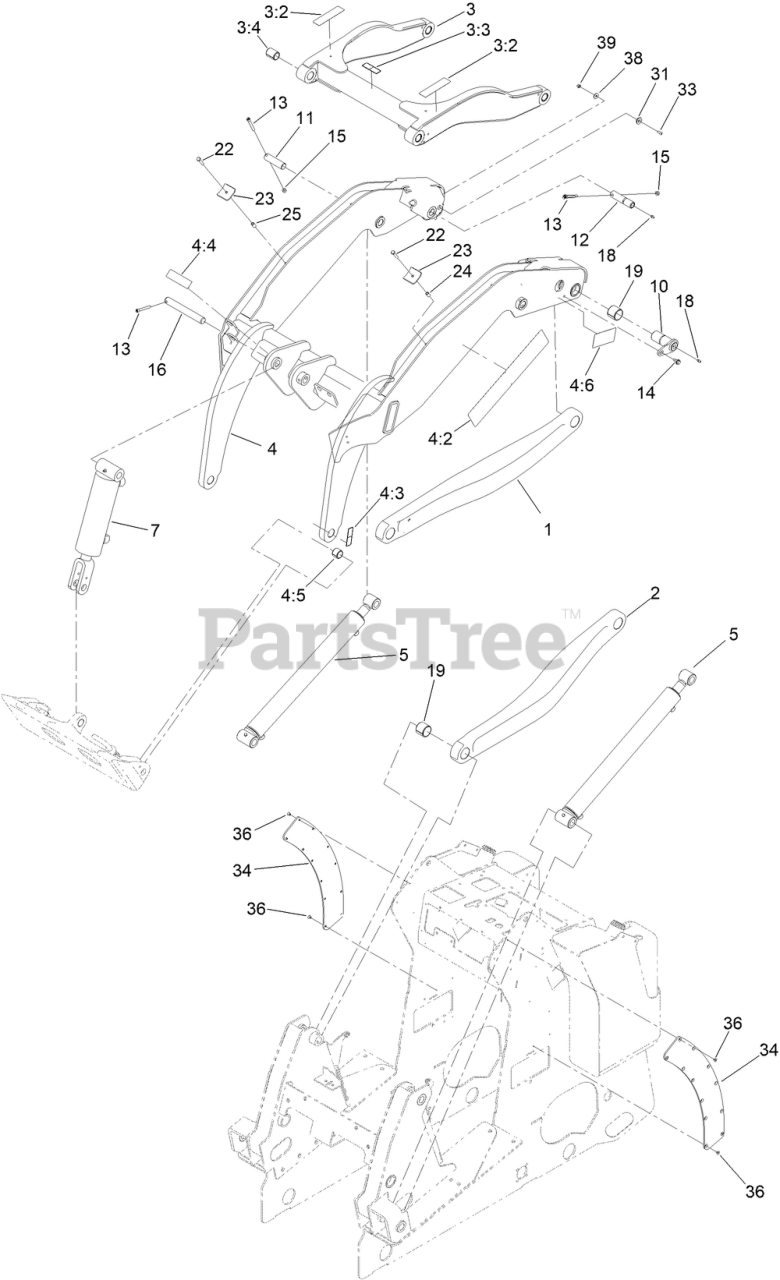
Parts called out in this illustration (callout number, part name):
1	LINK-LOWER, LH
2	LINK-LOWER, RH
3	LINK-UPPER
3:2	DECAL-WARNING, CRUSHING
3:3	DECAL-WARNING, PINCH POINT
3:4	BUSHING-SPRING
4	ARM-LOADER
4:2	DECAL-TX1000,
4:3	DECAL-WARNING, PINCH POINT
4:4	DECAL-CAUTION
4:5	BUSHING-TENSION
4:6	DECAL-WARNING, PINCH POINT
5	CYLINDER HYD (2.25X20.16 DOUBLE ACTION)
7	CYL-HYD
10	PIN-PIVOT
11	PIN-PIVOT
12	PIN-LINK
13	SCREW-HSH
14	BOLT-SHOULDER
15	NUT-LOCK, NI
16	PIN-LOCKING
18	FITTING-GREASE
19	BUSHING-SPRING
22	SCREW-HH
23	PLATE-HOLDDOWN, HOSE
24	SPACER-HOSE
25	SPACER-HOSE
33	SCREW-HSBH
34	PAD-WEAR, FRAME
36	SCREW
38	WASHER-PLAIN
39	NUT-LOCK, NI
